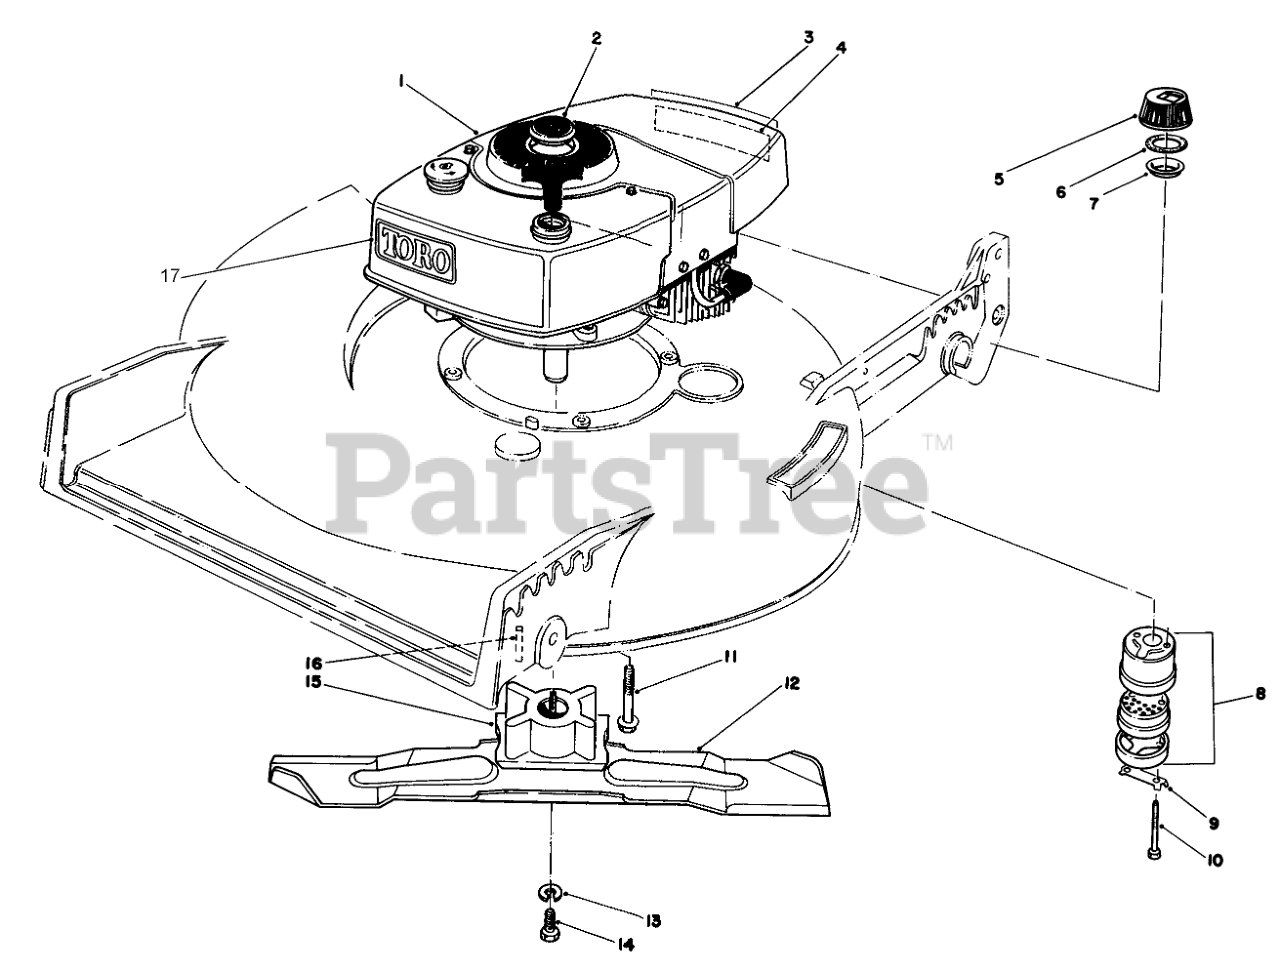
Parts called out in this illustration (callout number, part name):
1	Engine
2	Plug Button
3	Decal-Primer
4	Decal Maintenance
5	Gas Cap Assembly (Incl. Ref. #6 & 7)
6	GASKET
7	Baffle-Gas Cap
8	Muffler Assembly (Incl Ref. #9 & 10)
9	CLIP - LOCKING
10	SCREW-HH
11	3/8-16 X 2 CAPSCREW
12	BLADE-21in
13	WASHER-LOCK
14	SCREW-BLADE
15	BLADE RETAINER(DEEP)
16	KEY-SQUARE
17	Decal Tow
